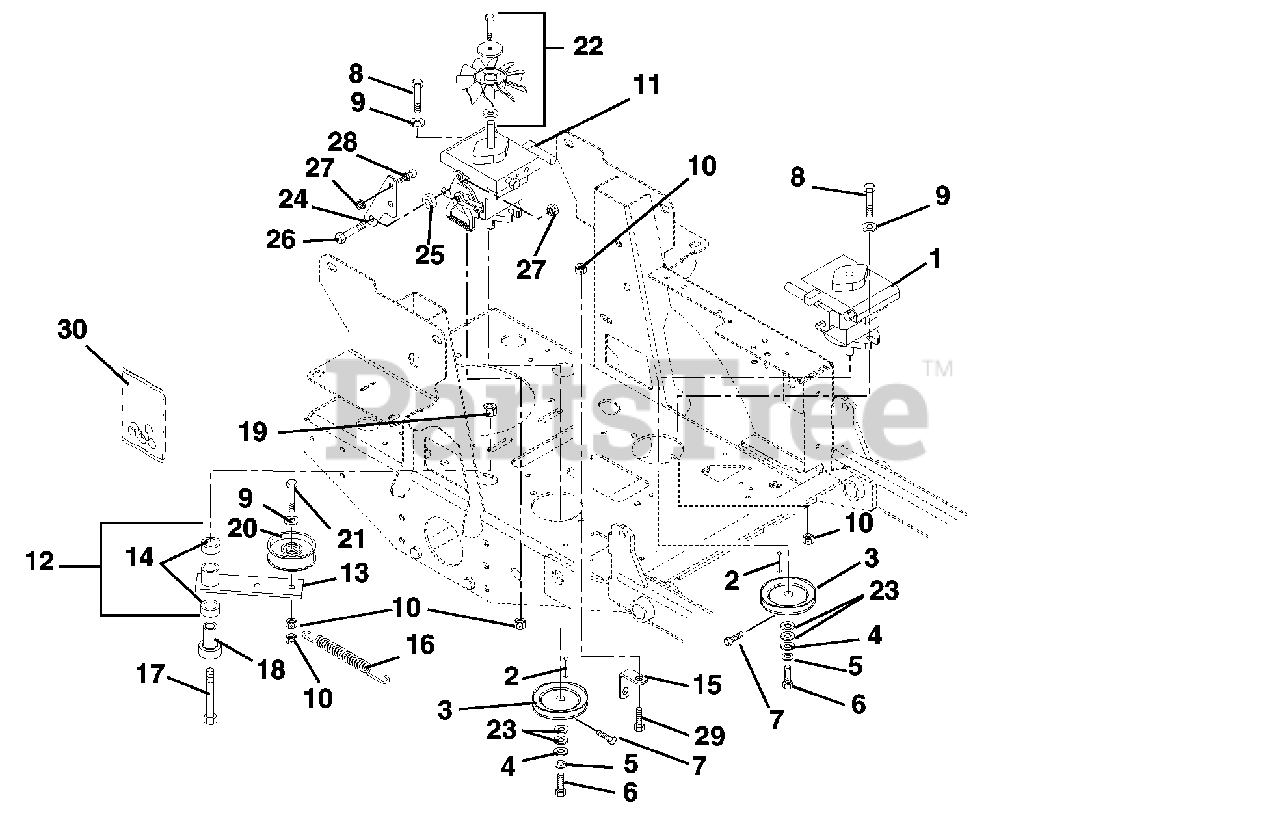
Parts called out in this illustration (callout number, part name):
1	Pump, Hydraulic BDP-10A Left Hand
2	Key, Straight 5mm x 25mm x 5mm
3	Sheave 4.0 x .199
4	Washer, Flat Steel .281 x 1.00 x .063
5	Washer, Locking .25 x .062
6	Bolt, Hex M6 x 1.00 x 12
7	Bolt, Hex .25-20 x .50 Grade 5
8	Bolt, Hex .38-16 x 1.25 Grade 5
9	Washer, Flat Steel .39 x .75 x .125
10	Nut, Locking Top Flange .38-16
11	Pump, Hydraulic BDP-10A Right Hand
12	Assembly,Idler Arm Guard Drive
13	Weldment, Idler Arm Ground Drive
14	Bearing, 1.00 x 1.12 x .75
15	Anchor, Spring Idler
16	Spring, Tension .120 x .845 x 6.50
17	Bolt, Hex .50-13 x 3.50 Grade 5
18	Bearing, Pedestal Powdered Metal
19	Nut, Locking Top Flange .50-13
20	Idler, Flat 4.00 x 1.06
21	Bolt, Hex .38-16 x 2.25 Grade 5
22	Fan, Cooling
23	Washer, Flat Steel .656 x 1.31 x .095
24	Bracket, Return to Neutral/Damper
25	Spacer .344 x 1.00 x .375
26	Bolt, Hex .31-18 x 1.25 Grade 5
27	Nut, Locking Top Flange .31-18
28	Stud, Ball
29	Bolt, Hex .38-16 x 1.00 Grade 5
30	Kit, Pump Seal (BDP-10A)
